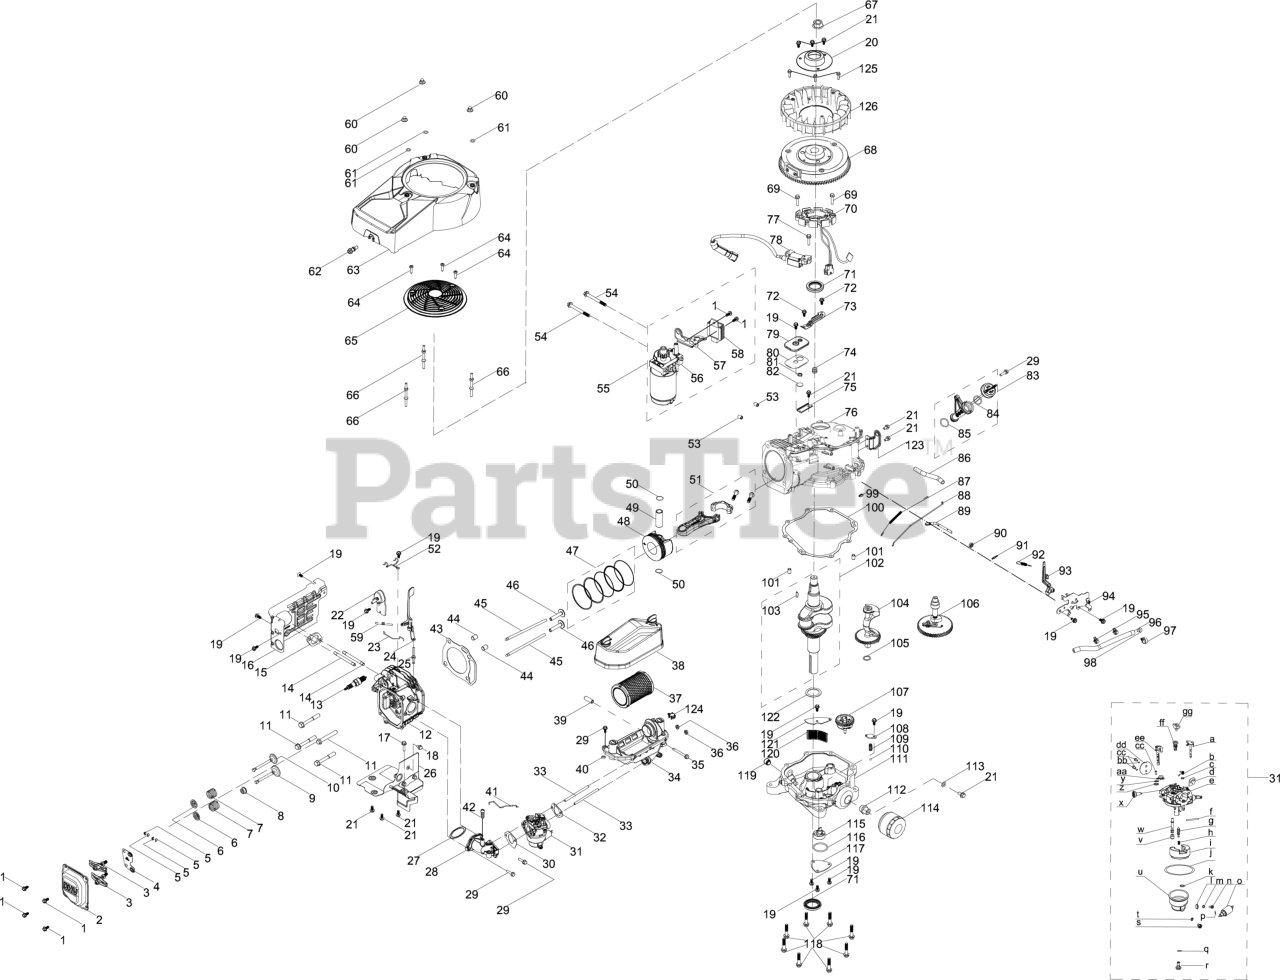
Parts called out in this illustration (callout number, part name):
1	BOLT M6x16
2	VALVE COVER
3	ROCKER ARM ASSEMBLY
4	ROCKER ARM BASE
5	VALVE CAP
6	VALVE SPRING SEAT
7	VALVE SPRING
8	INTAKE VALVE SEAL
9	INTAKE VALVE
10	EXHAUST VALVE
11	BOLT M10x1.25x70
12	CYLINDER HEAD
13	SPARK PLUG (F6RTC/RN11YC/BPR6ES)
15	EXHAUST GASKET
16	ENGINE SHROUD
17	BOLT M6x25
18	BOLT M6x10
19	BOLT M6x14
20	FLYWHEEL HUB COVER
21	BOLT M6x12
22	Thermal Switch
23	THERMAL LEVER
24	AIRVANE CHOKE
25	PIVOT VANE STUD
27	O-RING 36 x 2.5
28	CHOKE LEVER
29	BOLT M6x22
30	INTAKE GASKET
31	CARBURETOR
32	AIR FLTER GASKET
34	AIR FILTER BASE ASSEMBLY
35	BOLT M6x55
37	AIR FILTER W/PREFILTER
38	AIR FILTER COVER ASSEMBLY
39	BUSHING - 11X6X30
40	CARB FUEL DRAIN GASKET
41	CHOKE LEVER
42	SELF TAPPING SCREW 4.8-0.7x16
43	CYLINDER HEAD GASKET
45	PUSH ROD - INDIVIDUAL
46	TAPPET
47	PISTON RING SET
49	PISTON PIN
50	PISTON PIN SNAP RING
51	CONNECTING ROD ASSEMBLY
54	HEX FLANGE BOLT M8x80
55	Electric Starter
56	ELECTRIC STARTER ASSEMBLY
59	IDLE SPRING
60	ACORN NUT
64	SELF TAPPING BOLT 5.5x25
65	FLYWHEEL SCREEN
67	NUT M20 x 1.5
69	BOLT M5x28
70	ALTERNATOR
71	OIL SEAL - 35X52X7
72	HEX FLANGE BOLT M5x10
73	WIRE PLATE
75	BREATHER SCREEN
77	BOLT M6x28
78	IGNITION COIL
79	BREATHER COVER
80	BREATHER COVER GASKET
81	BREATHER VALVE SPRING
82	BREATHER VALVE
83	DIPSTICK ASSEMBLY
86	BREATHER HOSE
87	THROTTLE DAMPENING SPRING
88	THROTTLE LINKAGE
89	GOVERNOR GEAR SHAFT
90	GOVERNOR SEAL
91	COTTER PIN
92	GOVERNOR SPRING
93	GOVERNOR ARM ASSEMBLY
94	CONTROL BRACKET ASSEMBLY
95	HOSE CLAMP
96	FUEL HOSE 6.3 x 12.5 x 250
97	FUEL LINE SUPPORT CLAMP
100	CRANKCASE GASKET
101	DOWEL PIN 9 X 14
102	CRANKSHAFT
103	WOODRUFF KEY
104	BALANCE SHAFT
105	WASHER 17.2 x 26 x 1
106	CAMSHAFT ASSEMBLY
107	GOVERNOR GEAR
108	PRESSURE RELEASE COVER
109	PRESSURE RELEASE SPRING
110	OIL PUMP STEEL BALL
111	CRANKCASE COVER
112	OIL FILTER ADAPTER
113	WASHER - 6.2X1.5X13
114	ENGINE OIL FILTER
115	OIL PUMP ASSEMBLY
117	OIL SEPARATOR
118	BOLT M8 x 40
119	Earth Bolt
120	FILTER SCREEN
121	OIL SCREEN PLATE
122	WASHER - 35.4X1X52
126	COOLING FAN
